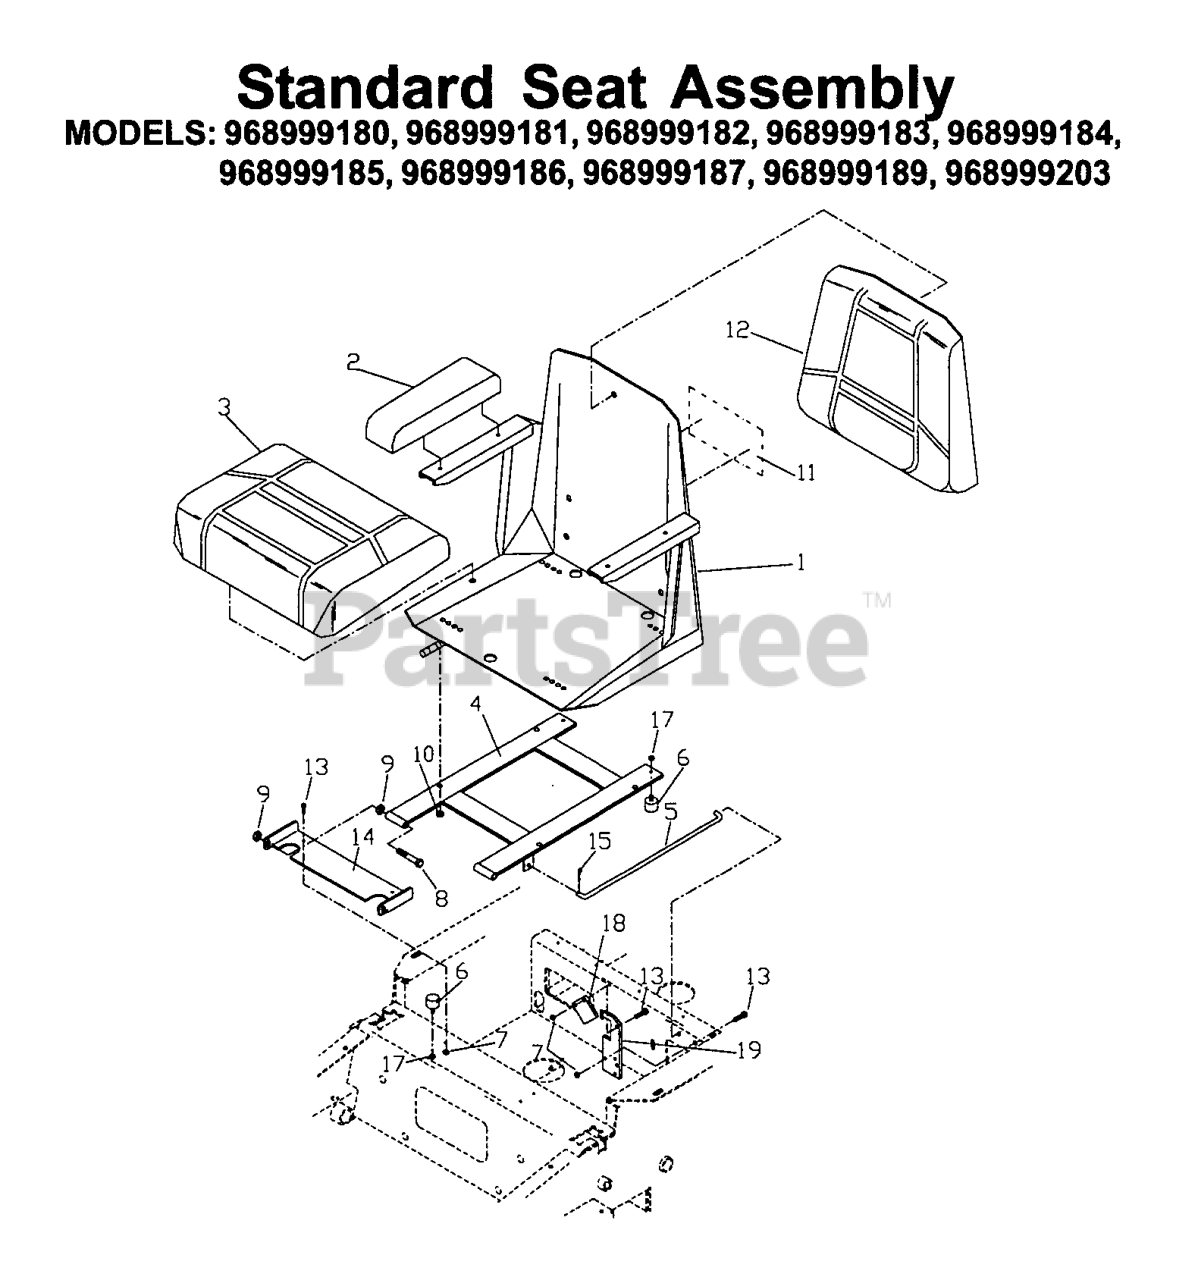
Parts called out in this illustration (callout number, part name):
1	SEAT, COMPLETE
2	ARM REST CUSHIONS/PAIR
3	SEAT CUSHION W/SWITCH
4	SEAT MOUNT
6	STUD/PLATE MOUNT
7	NUT 1/4C CENTER LOCK
8	HCS 3/8C X 3
9	NUT 3/8C CENTERBLOCK
10	NUT 5/16 NYLOC
11	DECAL, CROWN H
12	SEAT, BACK CUSHION
13	HCS 1/4C X 3/4 HCS
14	SEAT BRKT W/DECAL
15	RP_COTTER PIN 1/8 X 3/4
16	SEAT RAILS
17	NUT.1/4-20.HEX.NYLOC.ZD
18	SEAT LATCH
19	SEAT LATCH BASE
539105294	SEAT RAILS
